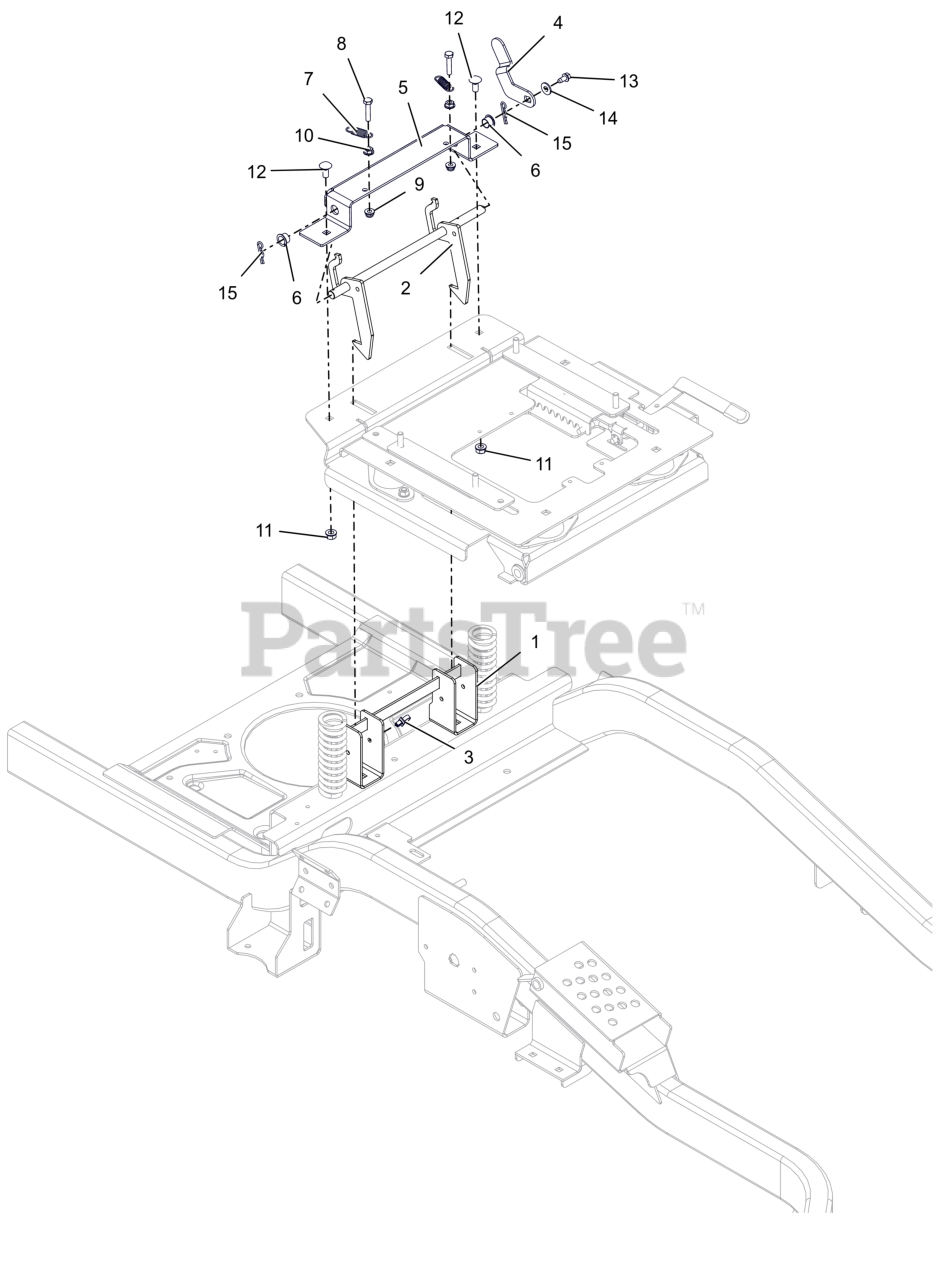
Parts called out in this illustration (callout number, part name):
1	WLDMT, LATCH RECEIVER
2	WLDMT, SEAT LATCH
3	ROUTING CLIP (1/2" ID)
4	LEVER, SEAT LATCH RELEASE
5	BRKT, SEAT HOOK MTG.
6	BUSHING, POLYLINER-.50 SPLIT
7	SG-TENS .063X.44X1.56
8	BLT, HEX .25-20X1.25 G5 ZCC
9	NUT,NYL-FLG .25-20 GF ZCC
10	NUT-SPNLK-FLG .25-20 ZC120
11	NUT,LK-CTR-FLG .31-18 GF ZCC
12	BLT,RHSN .31-18X.75 G5 ZCC
13	SCR-TAP .25-20X.50 HWH ZCC
14	WSHR, FLT .312X.734X.065 ZCC
15	PIN, HAIR .08X.38X1.42 ZCC
